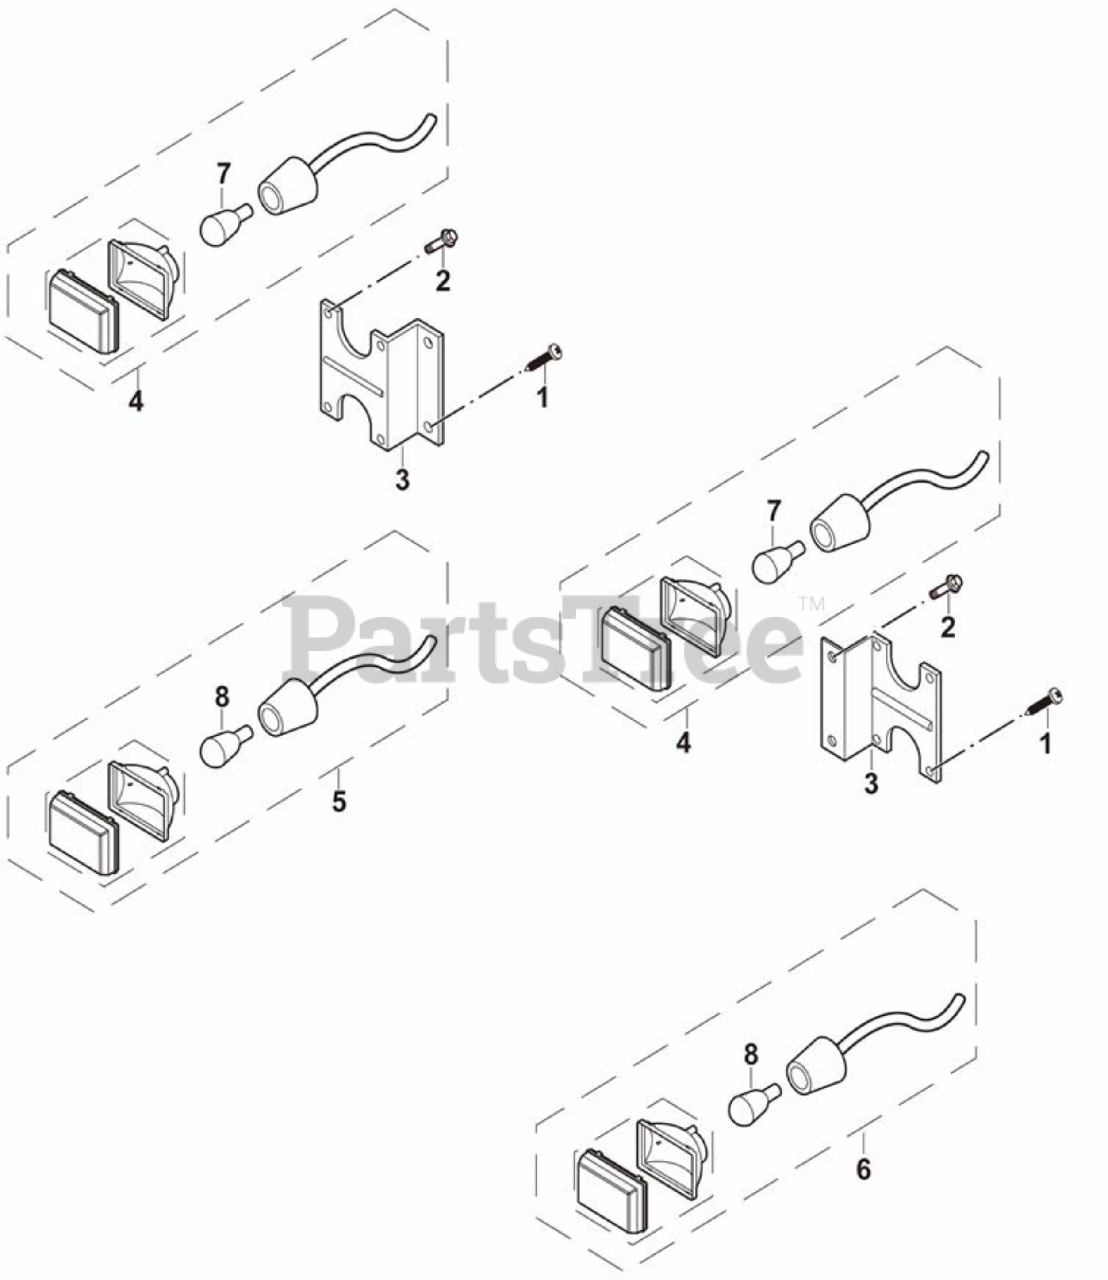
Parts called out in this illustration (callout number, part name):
1	Cross Small Plate Head Tapping Screw ST3.9X13
2	Cross Large Plate Head Screw M6X12
3	Mounting Plate, Tail Lamp
5	Rear Turning Light?L?
6	Rear Turning Light?R?
7	Tail lights bulb 12V?P21/W
8	Turning lights bulb ?12V?R10W
